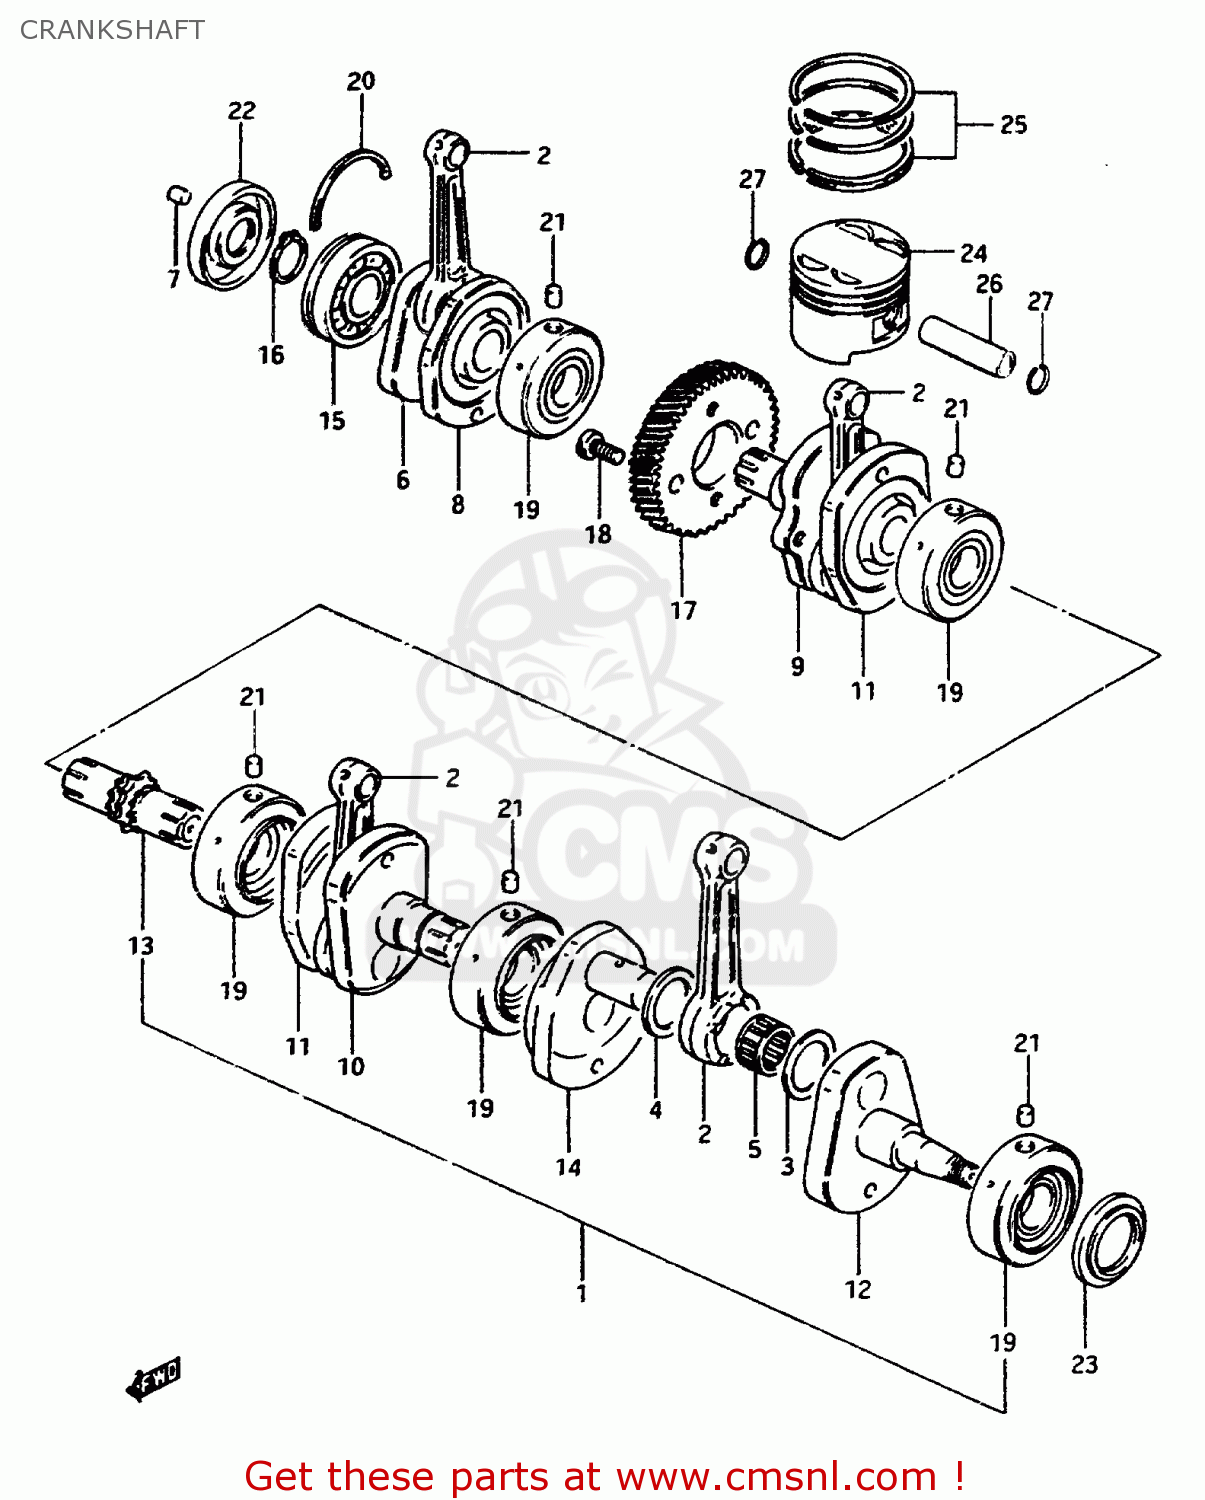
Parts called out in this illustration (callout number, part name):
1	CRANKSHAFT ASSEMBLY
2	ROD,CONNECTING
3	WASHER(31X48.5X1)
4	WASHER(31X48.5X2)
5	BEARING(31X39X21)
6	CRANKSHAFT,RIGHT
7	PIN
8	WEB,CRANK
9	CRANKSHAFT
10	CRANKSHAFT,MIDDLE,LEFT
11	WEB,CRANK,MIDDLE
12	CRANKSHAFT,LH
13	SHAFT,TIMING CHAIN DRIVE
14	WEB,CRANK,LEFT
15	BEARING(30X72X19)
16	CIRCLIP,30MM
17	GEAR,PRIMARY DRIVE
18	BOLT
19	BEARING(32X72X21)
20	C RING
21	PIN
22	SEAL,OIL(30X72X11)
23	SEAL,OIL(47.3X60X6.5)
24	PISTON (OS:0.5)
25	RING SET,PISTON
26	PIN,PISTON
27	CIRCLIP,PISTON PIN
